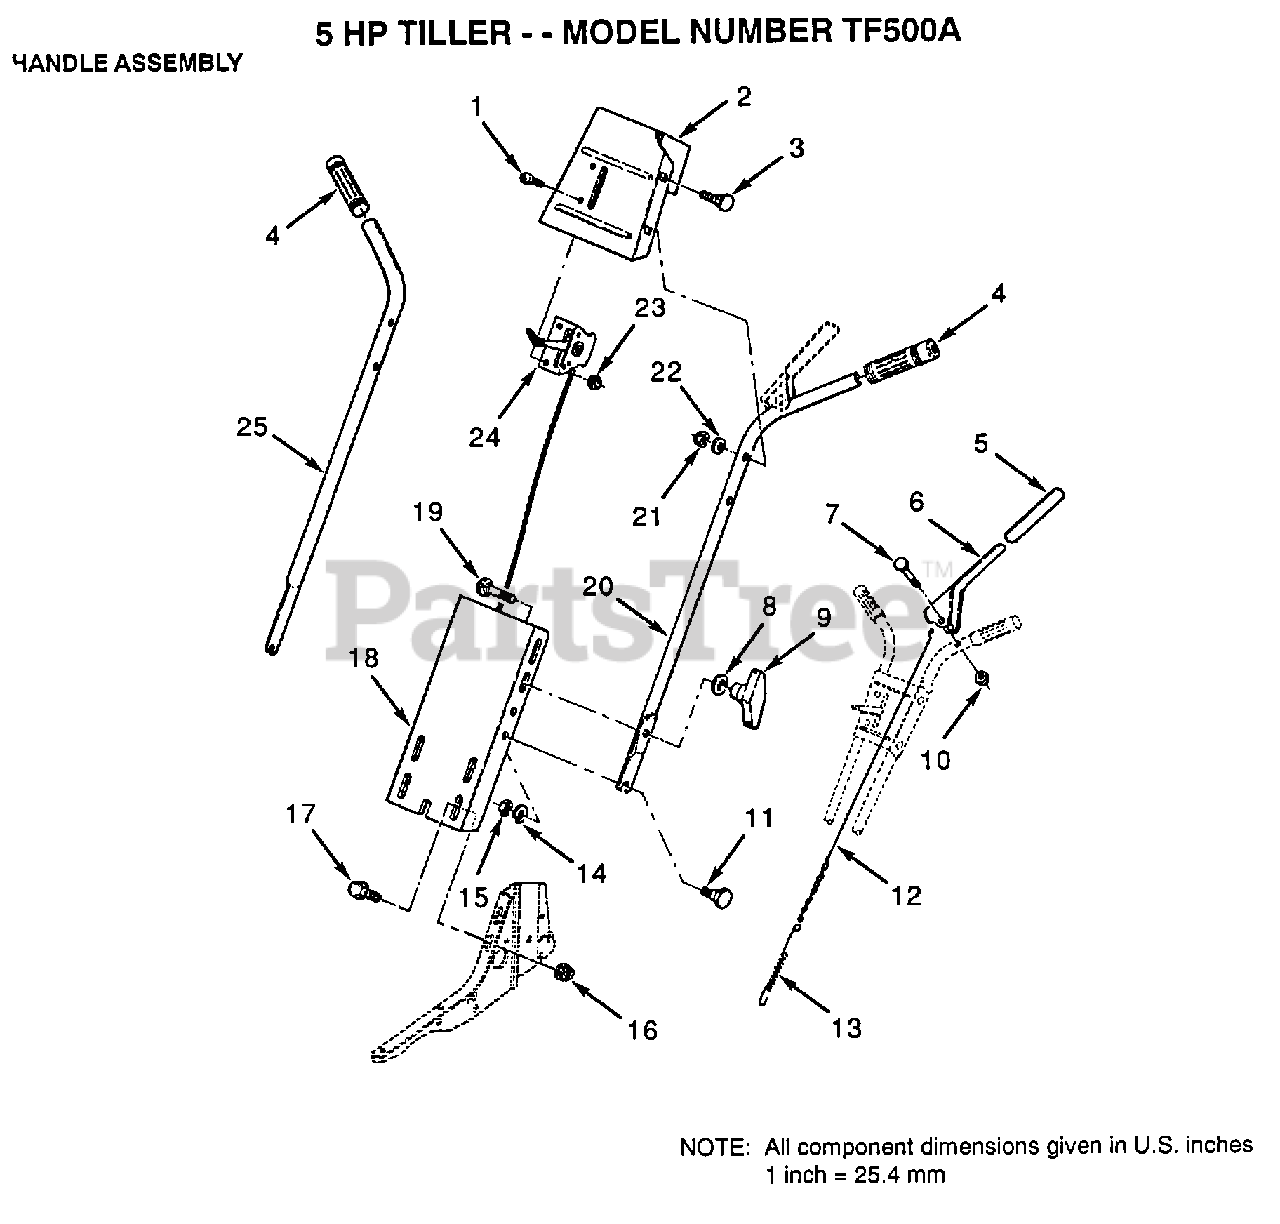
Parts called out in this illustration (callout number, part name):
1	SCREW
3	BOLT
5	GRIP T
7	BOLT.HEX.5/16-1.5
8	WASHER
13	SPRING EXT TI
14	LOCKWASHER
15	NUT.HEX.5/16-18
16	NUT
17	BOLT
18	"PANEL,HANDLE"
19	BOLT
22	WASHER
